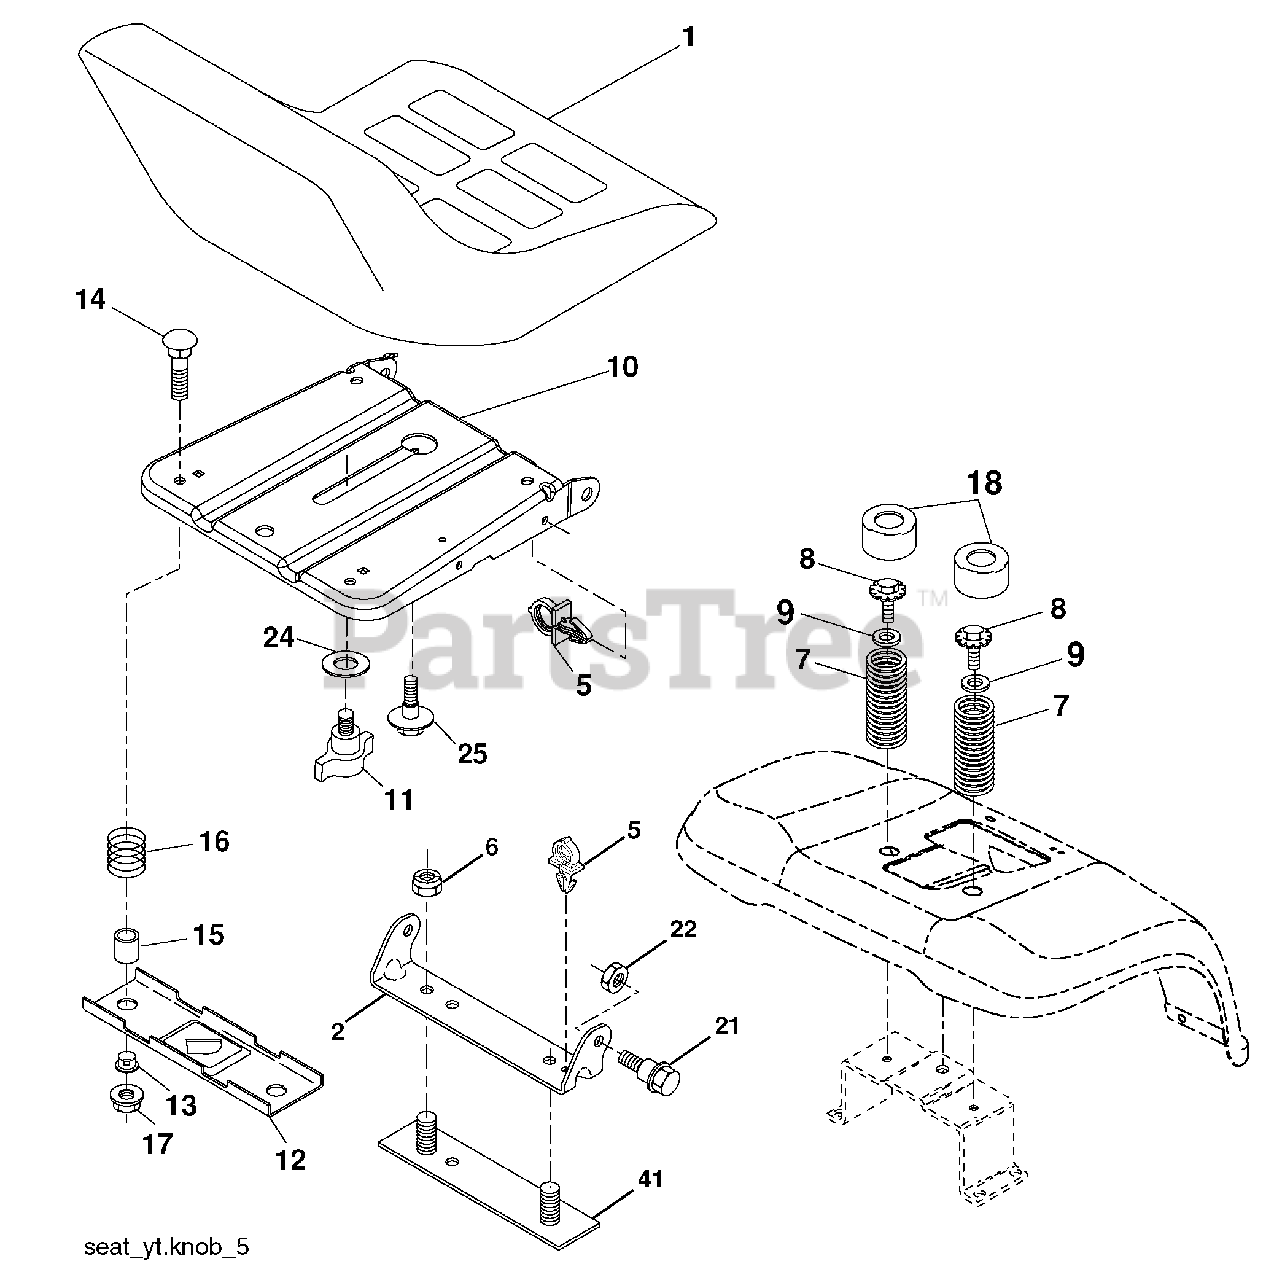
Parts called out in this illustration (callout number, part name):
1	Seat
2	Bracket Pivot Seat 8 720
5	Clip Push-In
6	Nut Hex w/Ins. 3/8-16 unc
7	Spring Seat Cprsn 2 250 Blk Zi
8	Screw 3/8-16 x 1.5 Smgml
9	Washer 13/32 x 1 x 14 Ga.
10	Pan Seat
11	Knob Seat
12	Bracket Mounting Switch
13	Bushing Snap Blk Nyl 50 Id
14	Bolt Rdhd Sqnk 1/4-20 x 1-1/2
15	Spacer Split 28x 88
16	Spring Cprsn
17	Nut Lock 1/4 Lge Flg Gr. 5 Zinc
18	Cap Spring Seat
21	Bolt Shoulder 5/16-18 unc
22	Nut Hex Lock W/Ins 5/16-18
24	Washer 17/32 x 1-3/16 x 12 Ga.
25	Bolt Shoulder 5/16-18 x 62
41	Strap Asm. Fender
